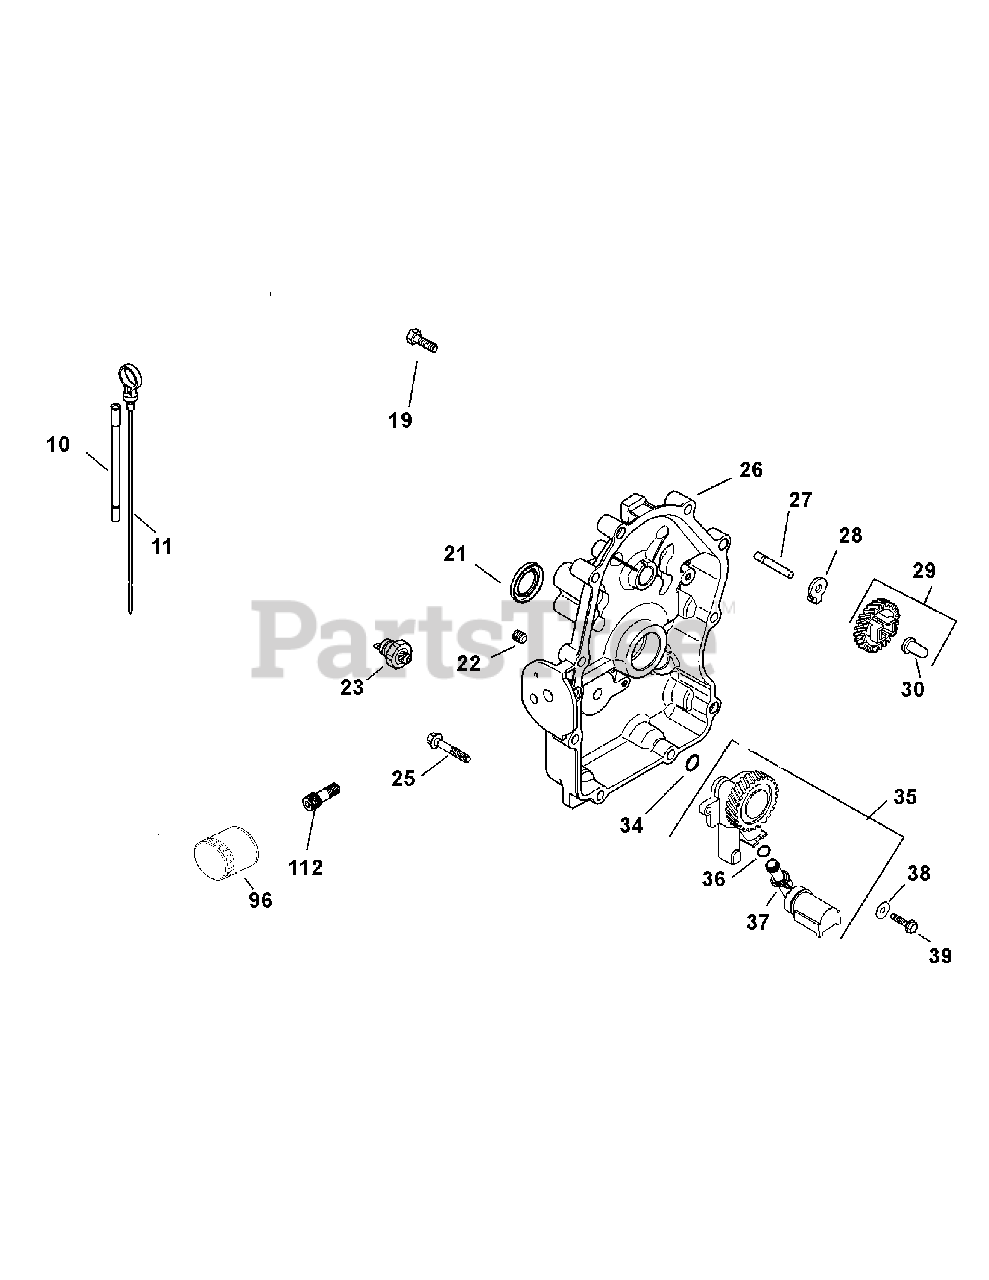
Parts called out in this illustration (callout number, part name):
10	Kit, Dipstick/Dipstick Tubes
19	Screw, Flg M8X1.25X45
22	Plug, Ctsk Pipe 1/8"
23	Switch, Oil Pressure
25	Screw, Flg M8X1.25X45
26	Plate, Closure & Bearing
27	Shaft, Governor Gear
29	Kit, Governor Gear W/Pin
30	Pin, Governor Regulating
35	Kit, Oil Pump Assy
36	O-Ring, Oil Pick-Up
37	Pick-Up, Oil
38	Washer, Flat 1/4" (O.D. 5/8")
39	Screw, Thread Forming
112	Nipple, Oil Filter
